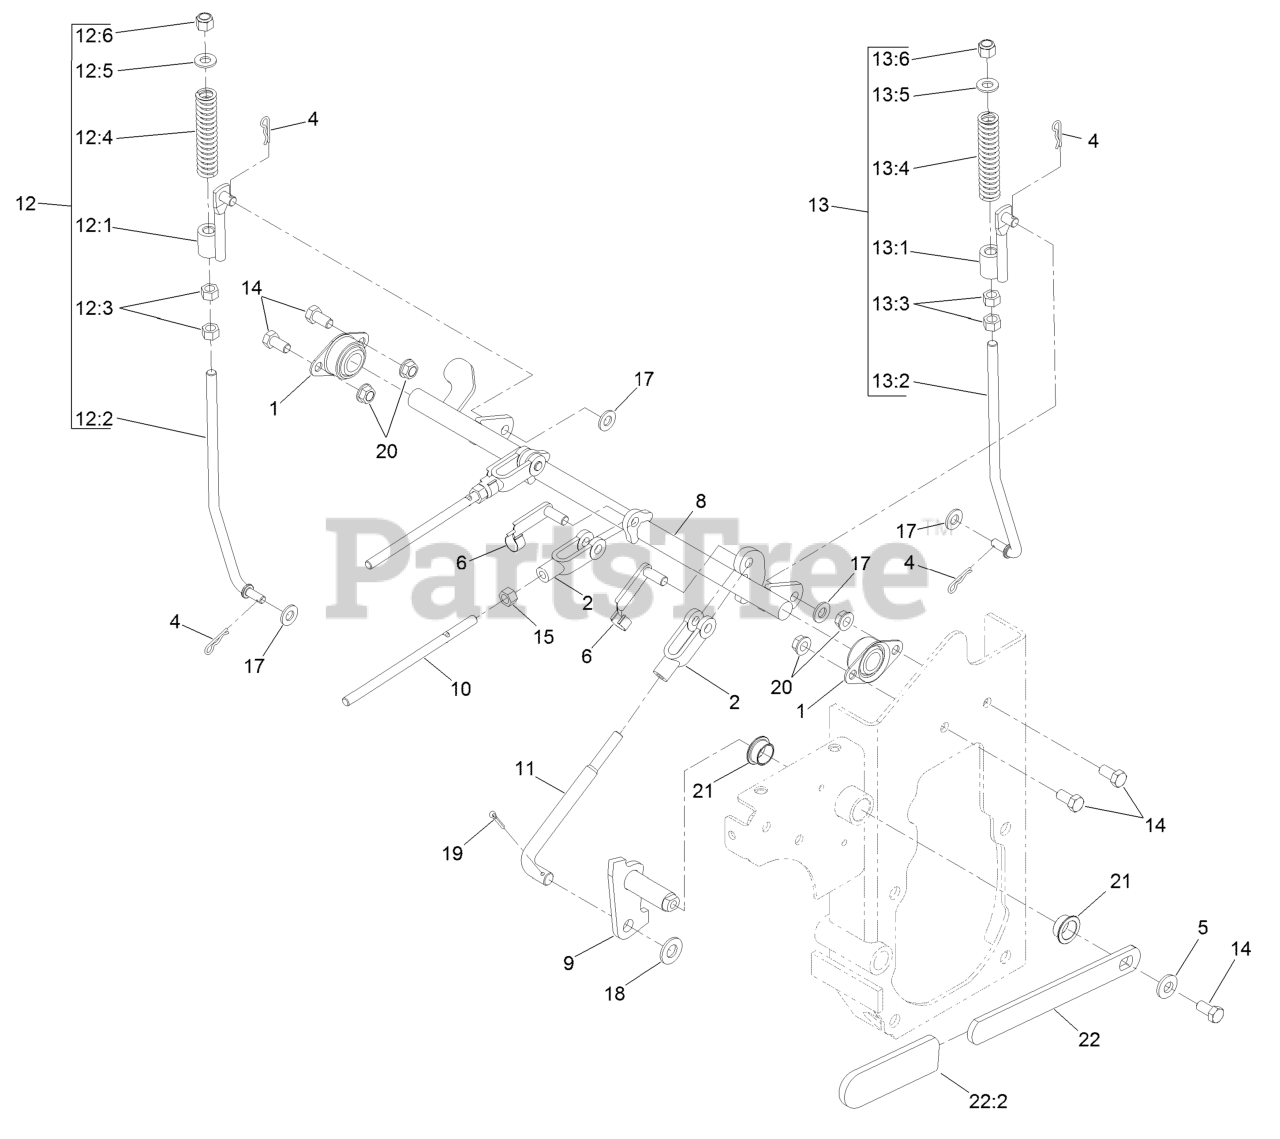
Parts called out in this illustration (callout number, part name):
1	BEARING-FLANGE, SIDE
2	YOKE-LINKAGE, BRAKE
4	PIN-COTTER
5	WASHER-BELLEVILLE
6	PIN-SPRING, CLEVIS
8	SHAFT-BRAKE
9	PIVOT-BRAKE
10	ROD-LINKAGE, BRAKE
11	ROD-LINKAGE, BRAKE
12	RH BRAKE LINKAGE ASM
12:1	BRAKE LINKAGE ASM
12:2	LINK-BRAKE, RH
12:3	NUT-HEX
12:4	SPRING-COMPRESSION
12:5	WASHER-FLAT
12:6	NUT-LOCK
13	LH BRAKE LINKAGE ASM
13:1	BRAKE LINKAGE ASM
13:2	LINK-BRAKE, LH
13:3	NUT-HEX
13:4	SPRING-COMPRESSION
13:5	WASHER-FLAT
13:6	NUT-LOCK
14	SCREW-HH
15	NUT-HEX
17	WASHER-FLAT
18	WASHER-FLAT
19	PIN-COTTER
20	NUT-HHF, WHIZ
21	BUSHING-BRONZE
22	PARK BRAKE HANDLE ASM
22:2	GRIP-LEVER
